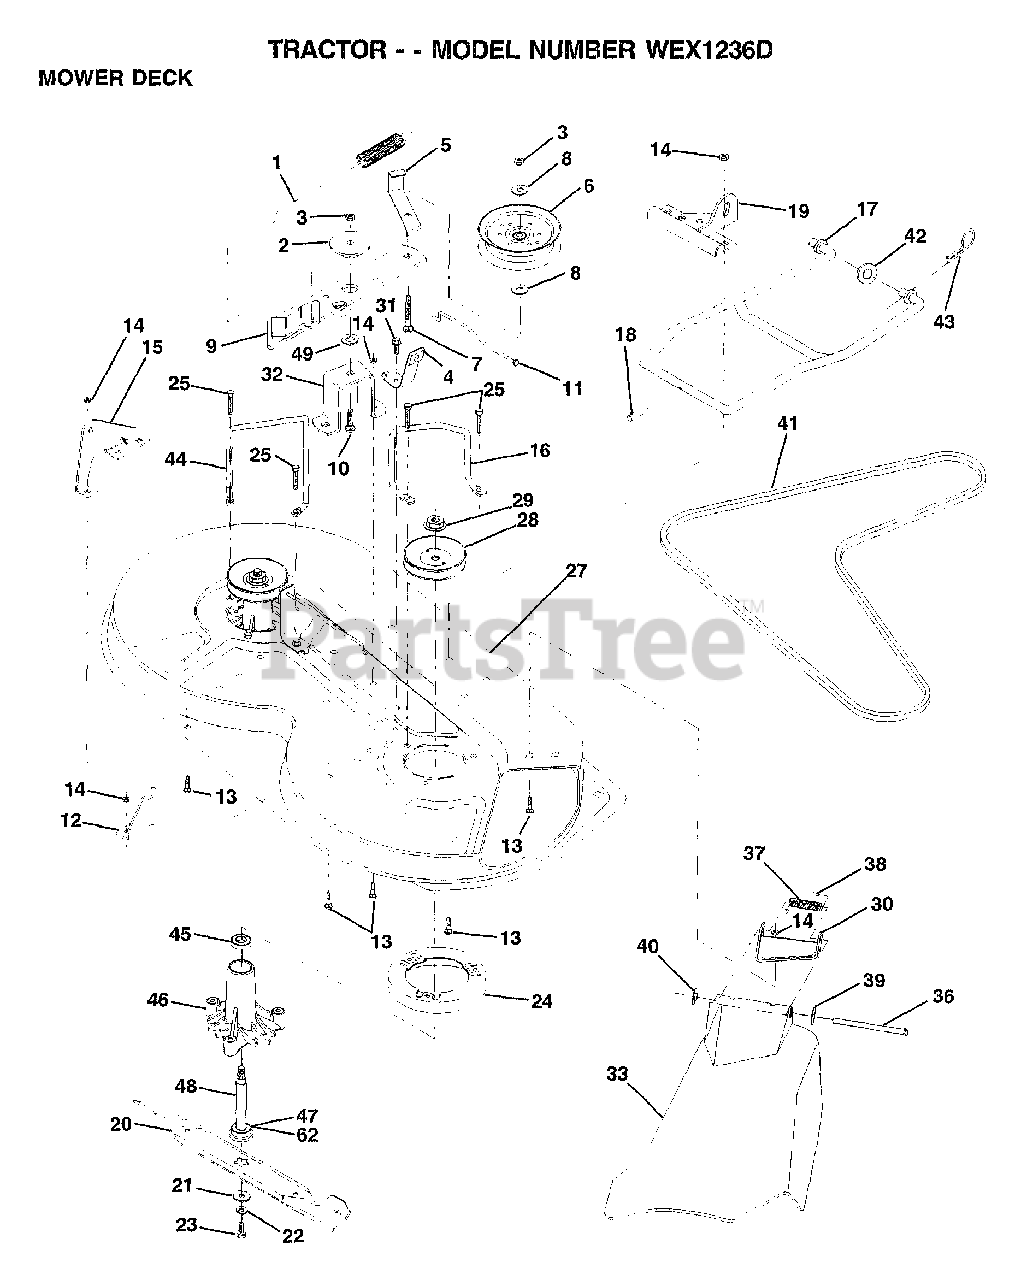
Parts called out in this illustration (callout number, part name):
1	SPRING CLUTCH MWR
2	SPACER.RETAINER.MOWER
4	BRAKE ASM
5	IDLER BELT GUIDE
6	PULLEY IDLER
7	BOLT
8	WASHER
10	BOLT.3/8-14X1.25
11	BRAKE ROD
12	"BRKT,LIFT REAR"
13	BOLT
15	"BRKT,LIFT REAR LH"
16	"KEEPER-BELT,RH"
17	MOWER LINK STAB
18	"PIN,GROOVE"
19	"BRKT,LINK STABILI"
20	"BLADE.36"" HIPERF"
21	WASHER.HARD.BLADE
23	BLADE BOLT
24	STRIPPER RND MWR
25	"SCREW-THD ROLL,WA"
27	"HOUSING-MOWER,36"""
28	PULLEY.MAND.36/46
31	SCREW LT
32	"SUPT,IDLER ARM"
33	SHIELD, DEFLECTOR
36	HINGE ROD
37	SPRING TORSION
38	CAP-SLEEVE LT
39	WASHER
40	NUT PUSH M
41	V-BELT.PRIM.78.5.
43	RETAINER SPRING
44	KEEPER BELT LH
45	BEARING
46	HSG ASM MANDREL
47	BEARING.BALL
49	HARDENED WASHER
62	WASHER.FELT.
